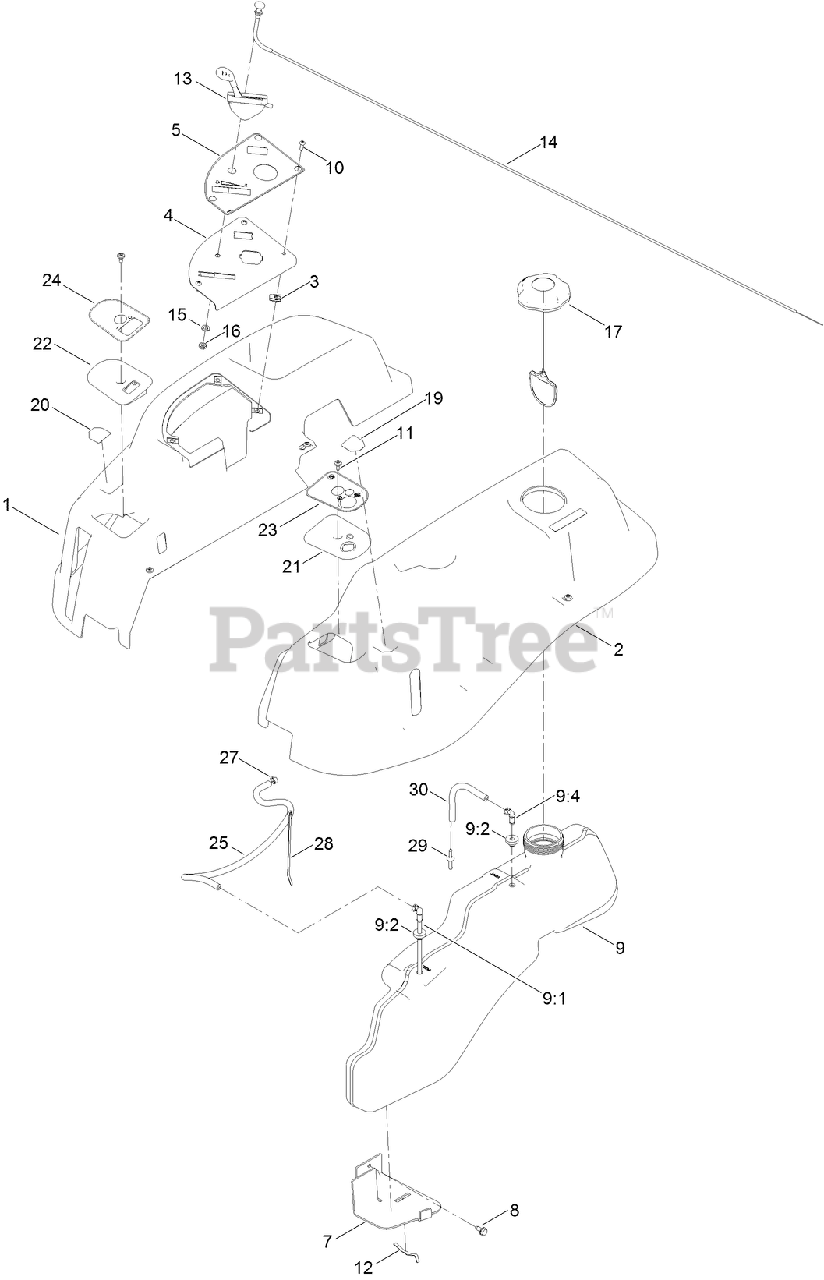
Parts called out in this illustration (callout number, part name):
1	POD-RH
2	POD-LH
4	PLATE-CONTROL
5	DECAL-PANEL, CONTROL
7	SUPPORT-TANK, FRONT
8	SCREW-HWHTF
9	FUEL TANK ASM
9:1	CONNECTOR-ELBOW, 90 DEG
9:2	BUSHING
9:4	FITTING-PLASTIC
10	SCREW-PRH
11	SCREW-SHOULDER
12	SPRING
13	CABLE-THROTTLE
14	CABLE-CHOKE
15	WASHER-LOCK
16	NUT-HJ
17	CAP-FUEL, RATCHETING
19	DECAL-NMIR
20	DECAL-CONTROL, PEDAL
21	COVER-LH
22	COVER-RH
23	DECAL-KEYCHOICE
24	DECAL-BRAKE, PARKING
25	HOSE-FUEL
27	CLAMP-HOSE
28	TIE-CABLE
29	ADAPTOR-ORIFICE
30	HOSE-FUEL
